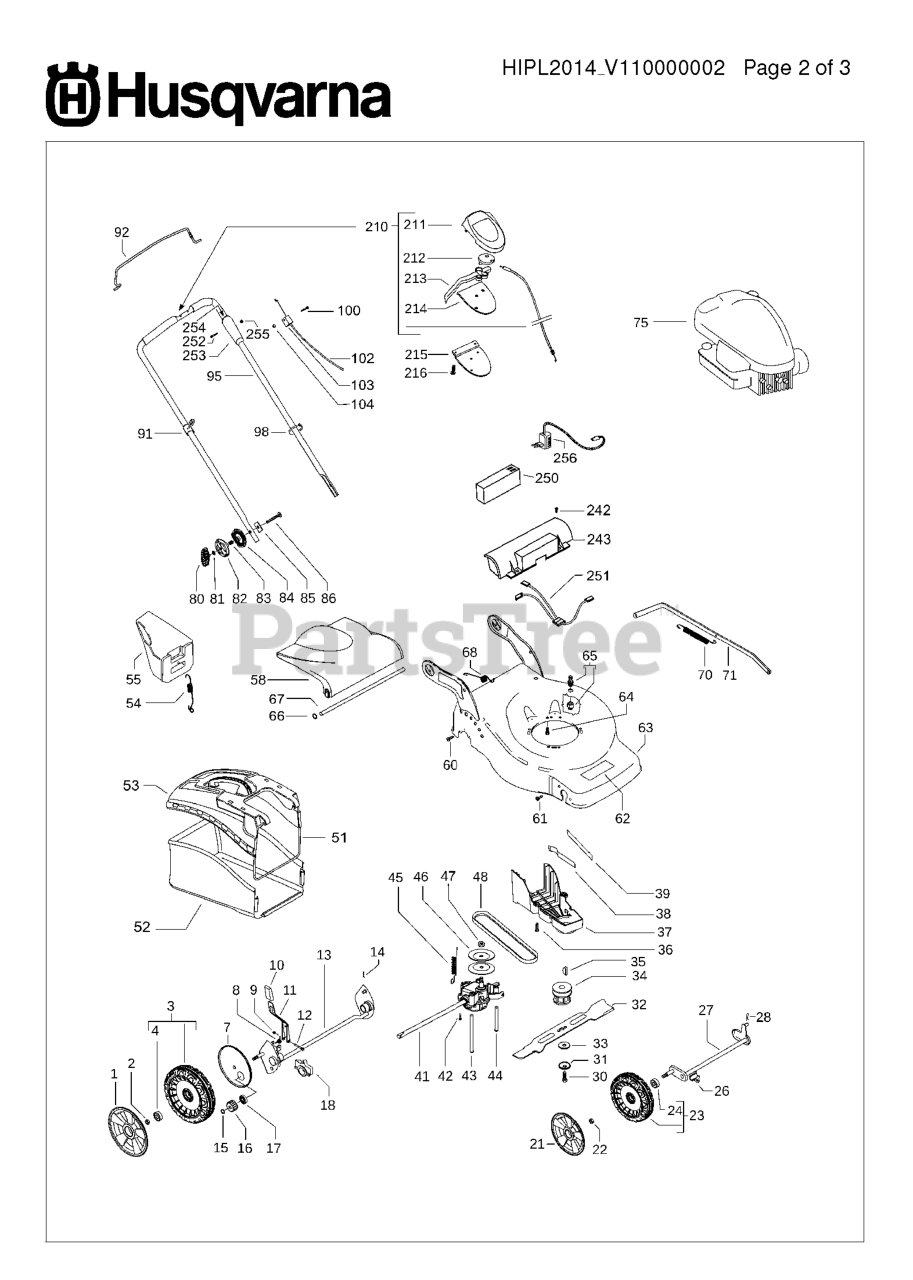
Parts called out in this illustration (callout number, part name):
32	MOWER BLADE COMBI
34	BLADE SUPPORT
95	HANDLE ASSY
102	BRAKE WIRE
211	COVER, DRIVE CONTROL, TOP
212	PULLEY.CAM.DRIVE.CONTROL.HV
213	LEVER, DRIVE CONTROL
214	COVER, DRIVE CONTROL BOTTOM
215	BRACKET, DRIVE CONTROL
216	SCREW, PHILLIPS HEAD 10 X 5/8
252	SCREW ITXSCM M6X40/25 T27 12.
253	RP CONTROLSH.BUTTON.START.22"
254	BUTTON.PUSHBUTTON.ES
255	LOCKNUT M6
256	CHARGER.BATTERY.CE
